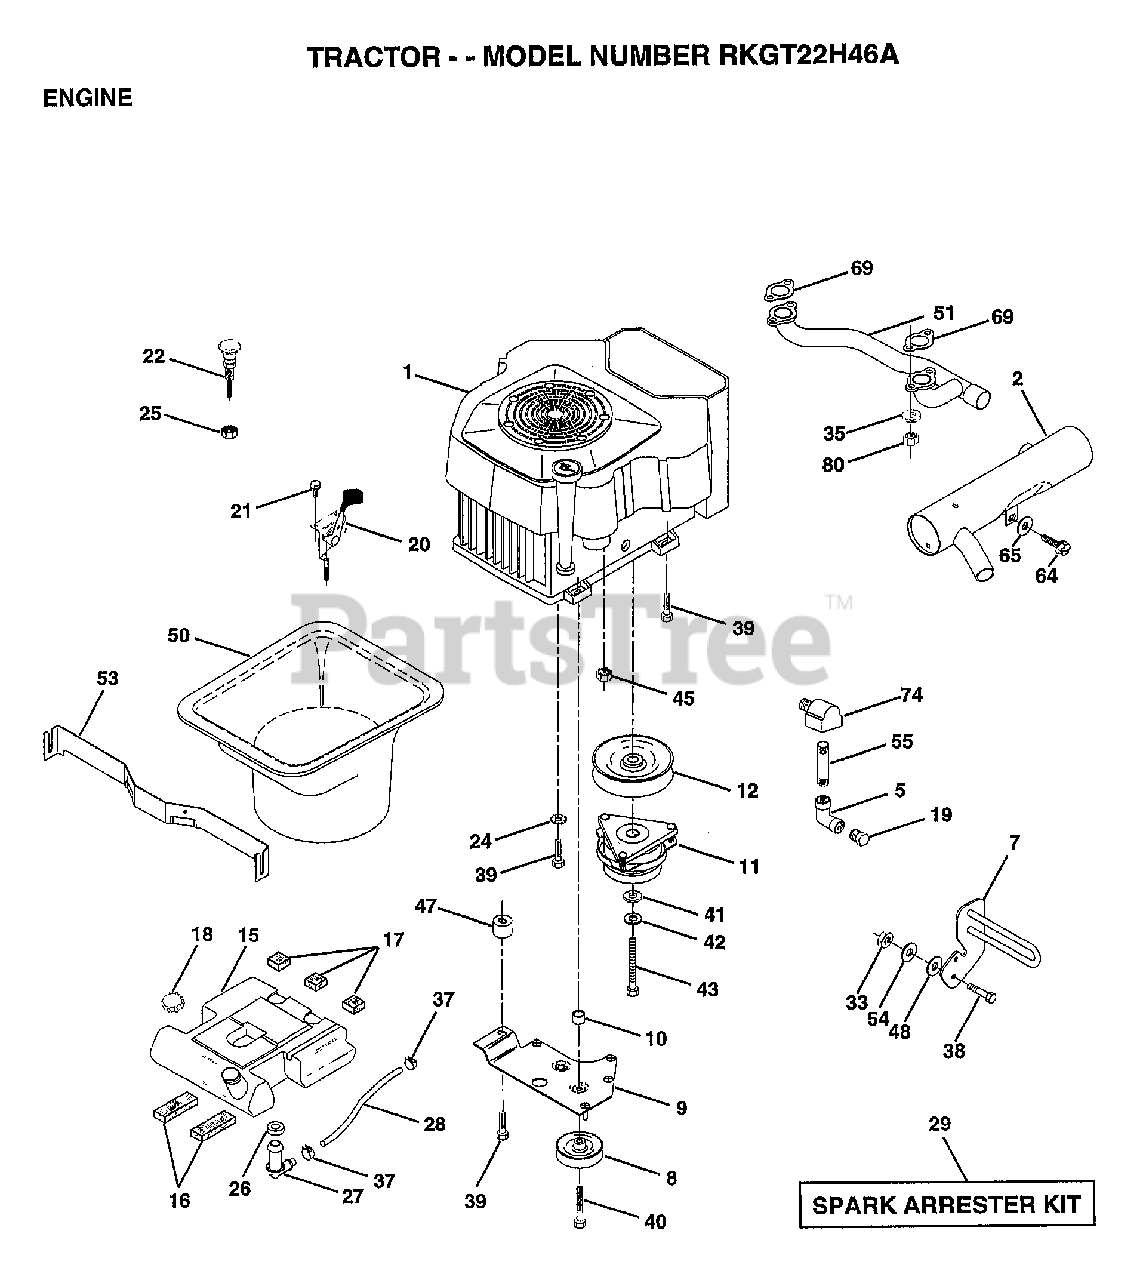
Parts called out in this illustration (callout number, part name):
2	MUFFLER.SIDE.VGT
5	ELBOW
7	GUARD.MUFFLER.ASM
9	KEEPER ASM BELT
10	BUSHING.
12	PULLEY.ENG.CLUTCH
15	TANK FUEL REAR
16	PAD IDLER TI
17	PAD-SPACER LT
18	CAP ASM FUEL
19	PLUG T
20	CONTROL.TRTL.37
21	SCREW LT
22	CHOKE CONTROL
24	LOCKWASHER
25	"NUT,KEPS 3/8-24IM"
26	BUSHING OUTLET T
27	STEM.TANK.FUEL
29	SPARK ARREST KIT
33	NUT
35	WASHER.SPLIT
37	HOSE CLAMP
38	"BOLT,HEX"
39	SCREW.3/8-16X2.25
40	SCREW.TT.3/8-16X4
41	WASHER
42	LOCKWASHER
43	BOLT.7/16-20X4.25
45	NUT
47	SPACER.ENGINE
48	WASHER T
50	DUCT AIR INTAKE
51	MANIFOLD.PIPE.VGT
53	ROD SUPT HOOD DUC
54	WASHER
55	PIPE NIPPLE LT
64	SCREW
65	WASHER
69	GASKET
74	ELBOW STREET BASS
80	NUT FLANGE M8-125
